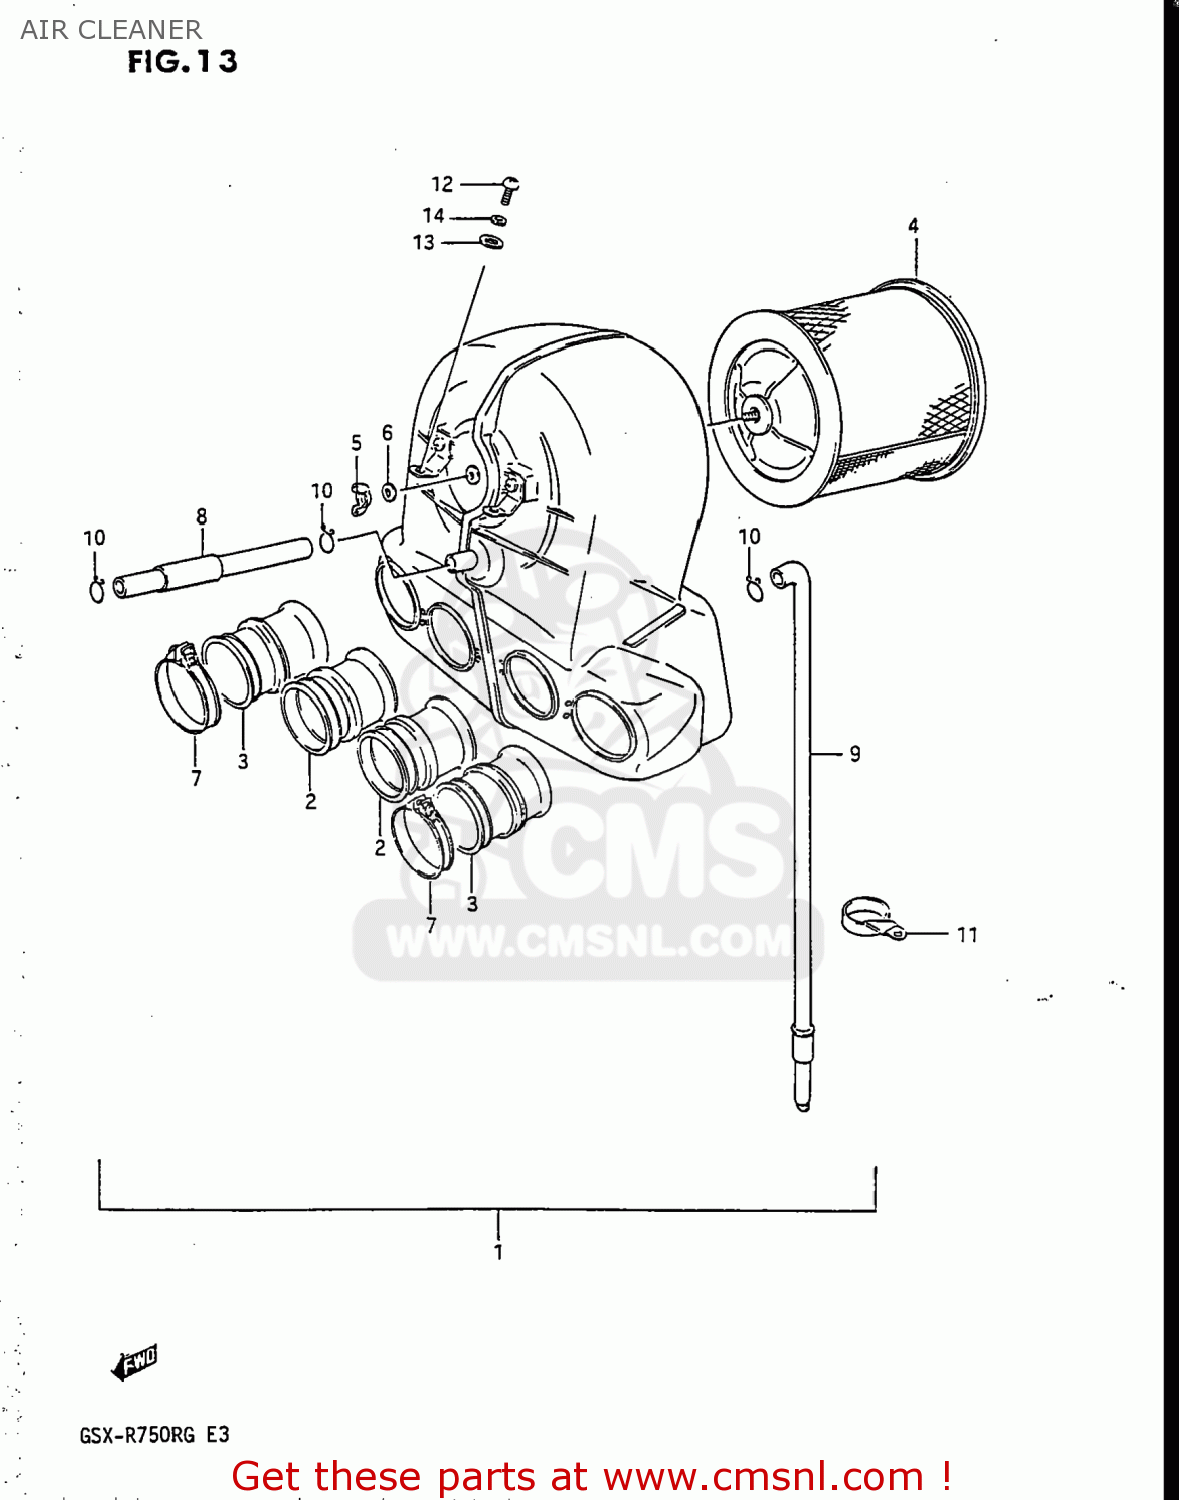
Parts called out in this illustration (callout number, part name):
1	CLEANER ASSY,AIR
2	TUBE,OUTLET NO.1
3	TUBE,OUTLET NO.2
4	FILTER ASSY,AIR
5	NUT, WING
6	WASHER 5MM
7	CLAMP
8	TUBE,BREATHER
9	DRAIN TUBE
10	CLIP
11	CLAMP,AIR CLEANER DRAIN TUBE
12	SCREW
13	WASHER(6.5X16X1.2)
14	WASHER,LOCK
